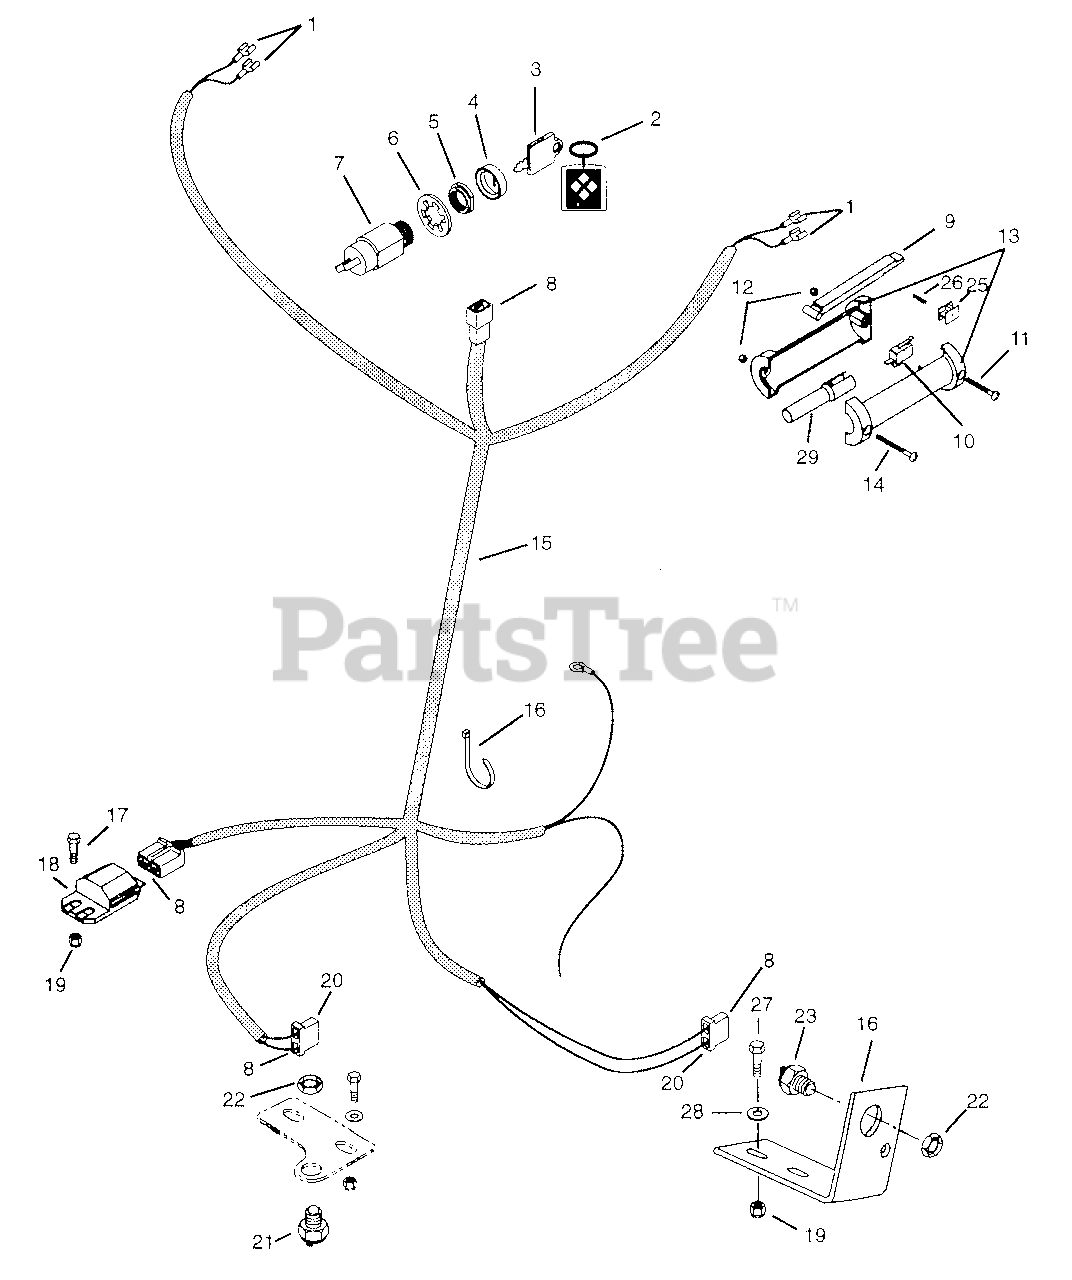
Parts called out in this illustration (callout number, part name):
1	Terminal
2	Key Chain
3	Ignition Switch Key
4	Cap-Ignition Switch
5	Nut-Panel .625-32
6	Washer, Lock Internal .625
7	Key Switch
8	Terminal
11	Screw-Machine 10-24 x .625
12	Nut-Locking 10-24
13	Handle, Left Hand & Right Hand
14	Screw-Machine 10-24 x 1.50
15	Harness, Wiring PRO-250 w/14 HP Kawasaki
16	Tie Wrap
17	Bolt-Hex .25-20 x .75 Grade 5
18	Module, Interlock, Recoil
19	Nut-Locking-Nylon .250-20
20	Connector-2 Wire Switch
21	Switch-Neutral N.O.
22	Nut-Stamped .56-18
23	Switch-Neutral Start N.C.
24	Bracket, Interlock Switch
25	Holder, Switch
26	Pin-Roll .094 x .750
27	Bolt-Hex .25-20 x .75 Grade 5
28	Washer-Flat-Steel .281 x .620 x .065
29	Insert, Handlebar
